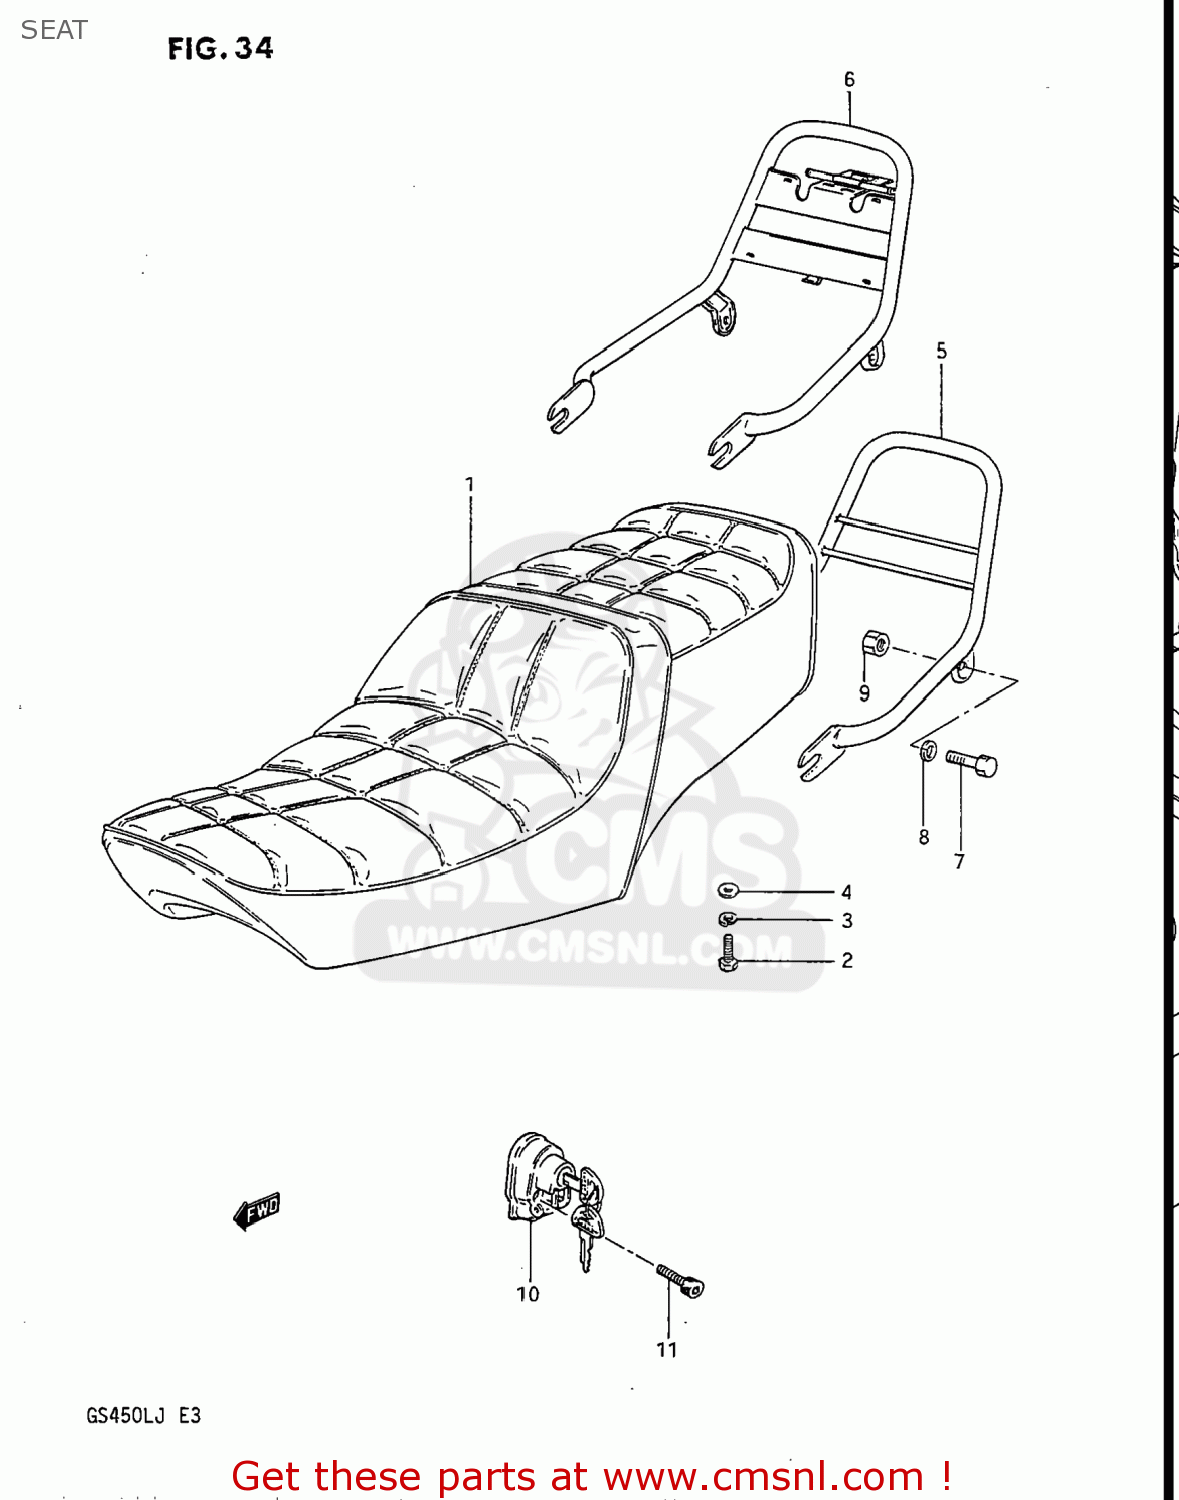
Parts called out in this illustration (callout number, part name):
1	SEAT ASSEMBLY
2	BOLT(6X20)
3	WASHER,LOCK
4	WASHER
5	HANDLE,PILLION RIDER
6	HANDLE,PILLION RIDER
7	BOLT
8	LOCK WASHER
9	NUT
10	LOCK ASSY,HELMET
11	BOLT
